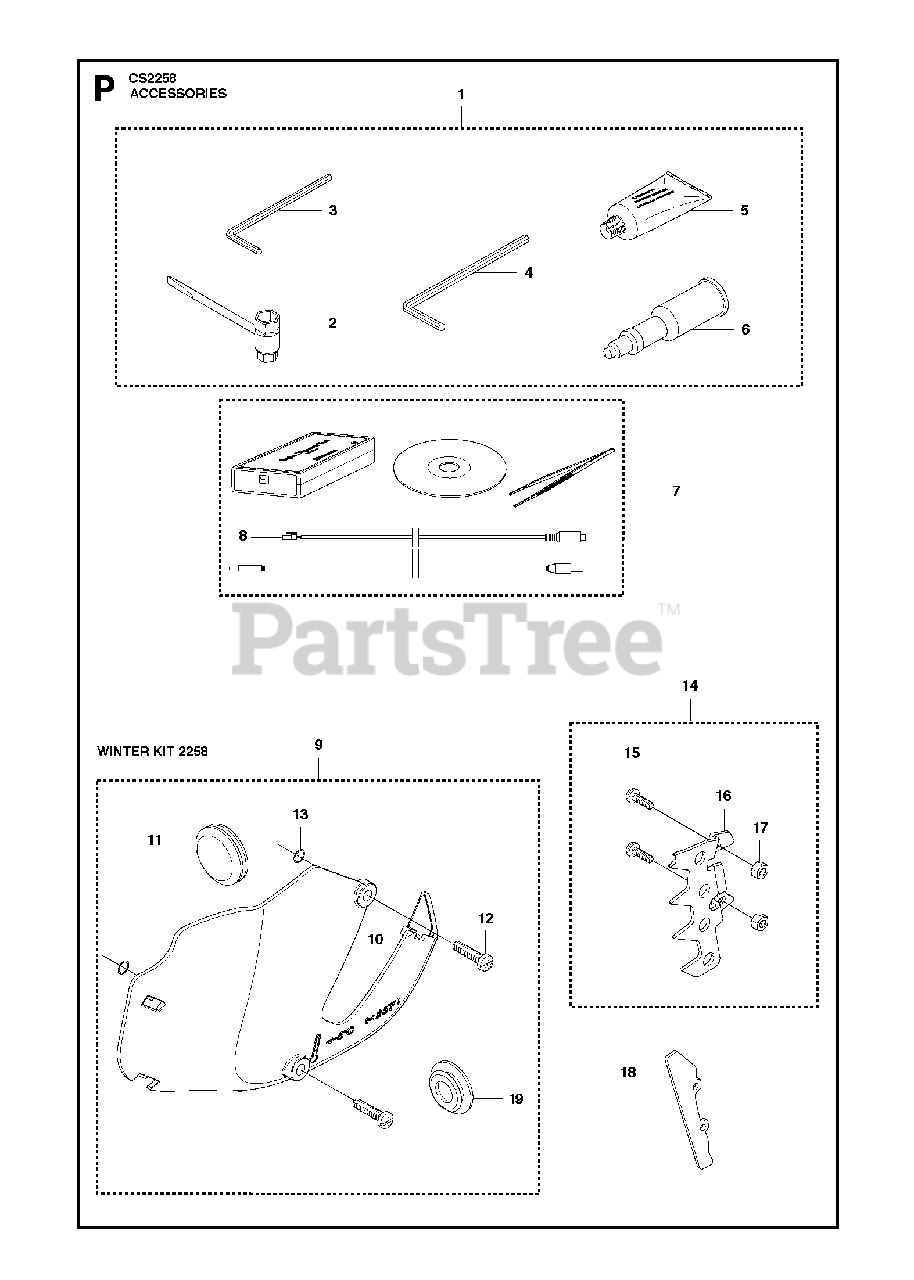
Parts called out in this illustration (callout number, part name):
2	COMBINATION WRENCH
3	L-SPANNER
4	L-SPANNER
5	GREASE
6	Grease Gun
7	SERVICE TOOLS
8	CABLE ASSY
9	WINTER KIT
10	WINTER COVER JONSERED
11	PLUG
12	SCREW
13	O-RING
14	SPIKE OUTER
15	SCREW
16	SPIKE OUTER
17	NUT
19	WINTER PLUG
